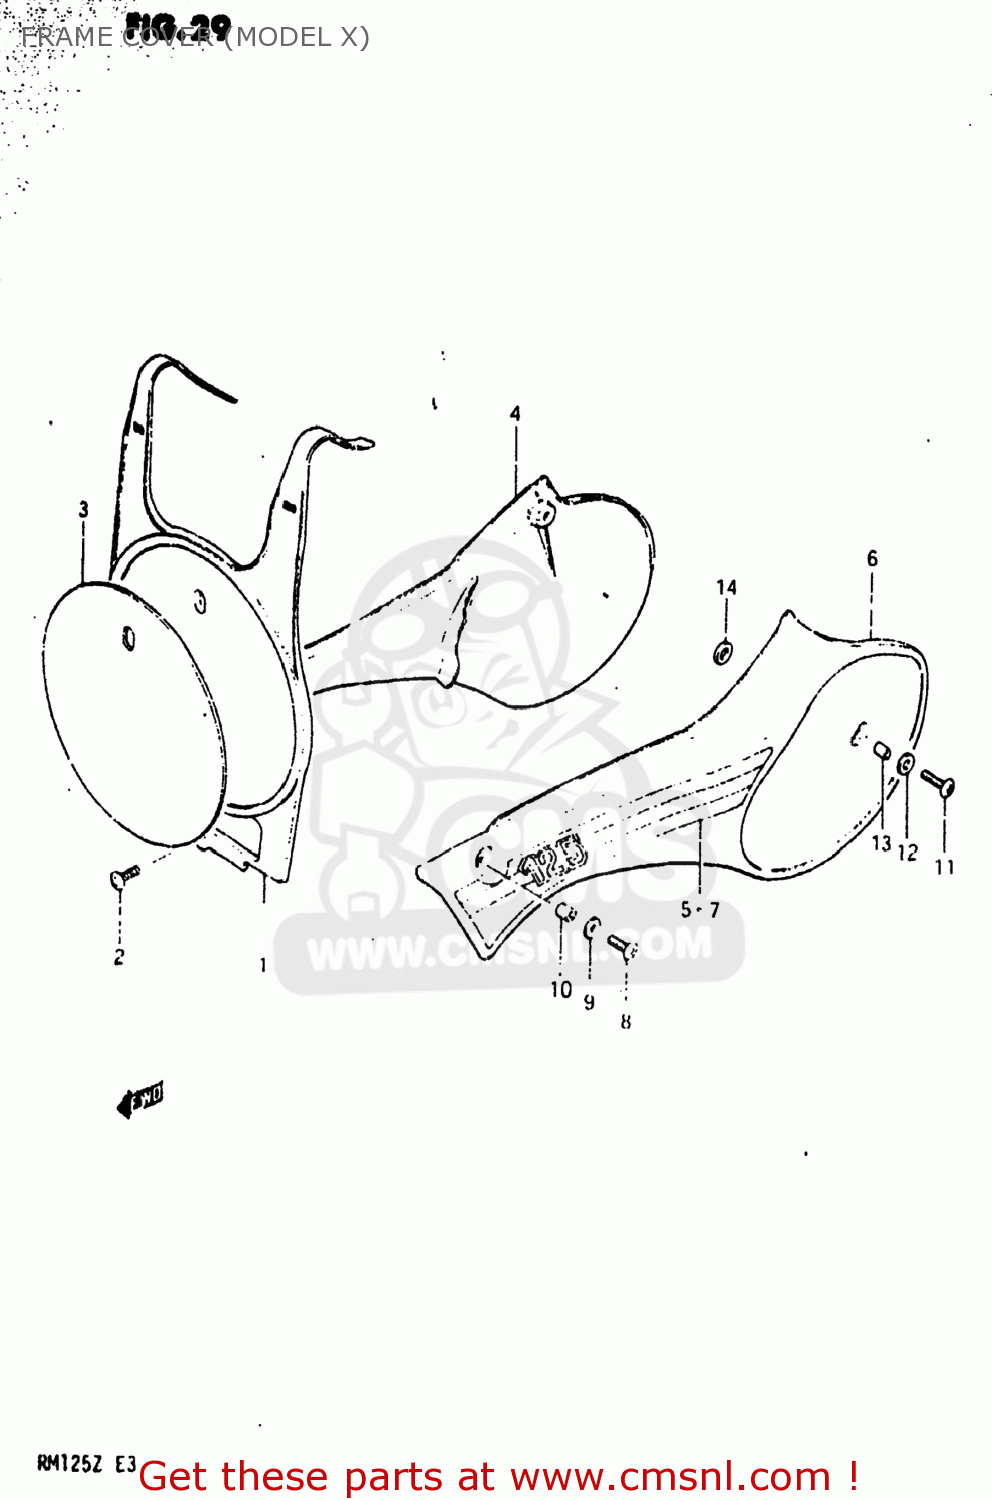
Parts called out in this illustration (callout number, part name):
1	PLATE,NUMBER,FRONT
2	(5X20) CROSS SCREW
3	EMBLEM,FRONT NUMBER PLATE
4	COVER,FRAME,RIGHT
5	TAPE,FRAME COVER
6	COVER,FRAME,LEFT
7	TAPE,FRAME COVER,LEFT
8	SCREW(6X25)
9	WASHER FRAME COVER
10	SPACER,FRAME COVER,FRONT
11	SCREW
12	WASHER FRAME COVER
13	SPACER FRAME COV RR
14	GASKET
